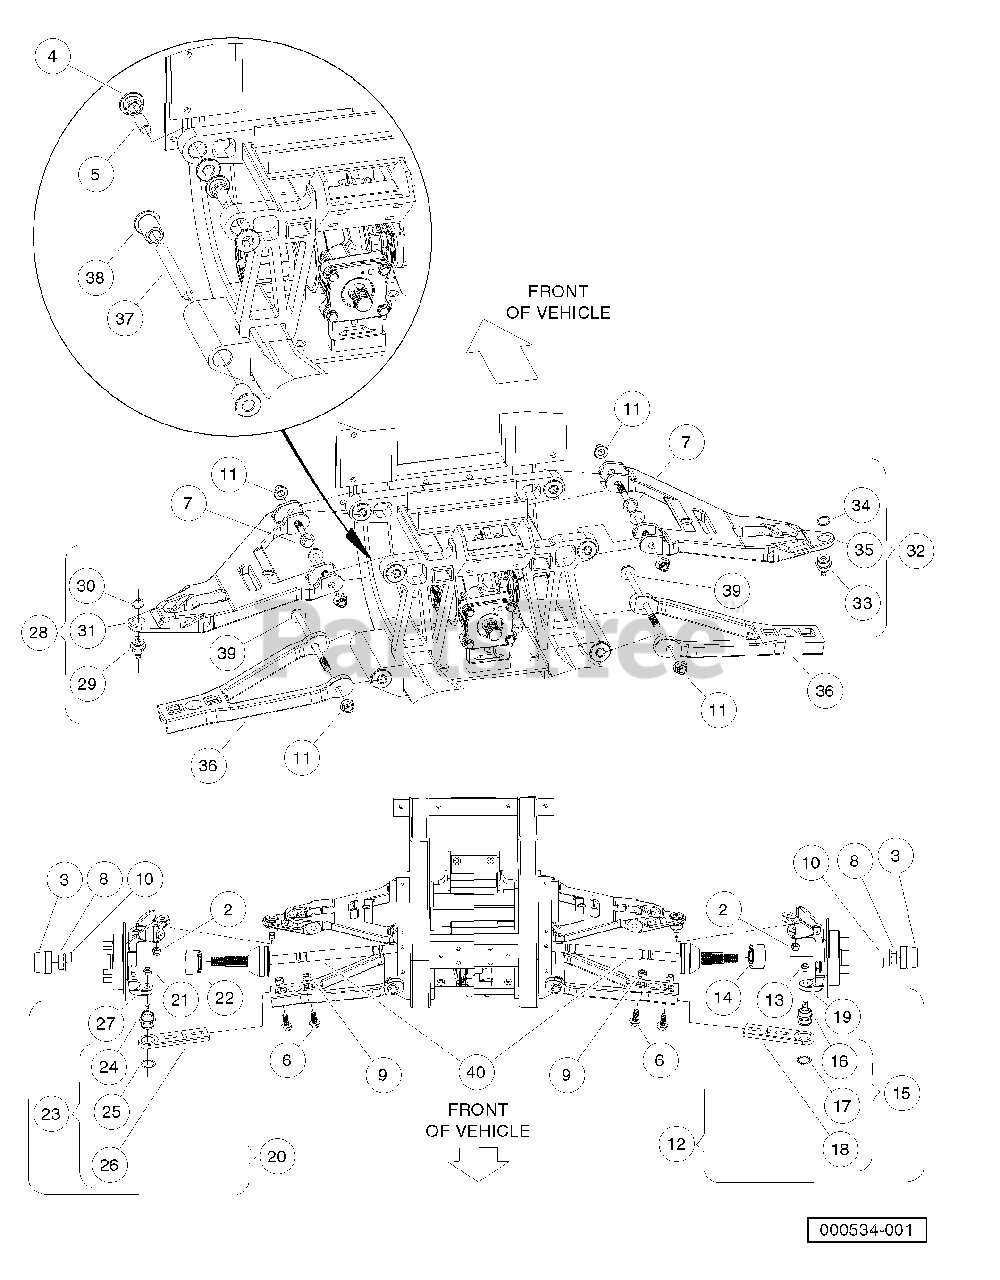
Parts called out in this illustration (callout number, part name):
1	Suspension, AWD, Wide
2	Locknut, M12-1.25 Nylon
3	Center Cap, Rubber
4	Bushing, A-Arm
5	Sleeve, Upper
6	Bolt, Flange Head, M12x 1.75x 30 with Loctite
7	Bolt, Flange Head, M12 X 1.75 X 70
8	Nut Flg, M22 X 1.5 Mech Def
9	Nut, Square, M12x 1.75
10	Washer Hard, M22
11	Nut Flg, M12x1.75, Nylon Gr 10
12	Upright, Left-Hand
13	Locknut, M12-1.25 Nylon
15	Asm, Adjuster, Slide
16	Joint, Ball
17	Ring, Retaining, Ext, 1-1/4"
18	Slide, Adjuster
19	Upright, Left, 40 X 74 X 40
20	Upright, Right-Hand
21	Locknut, M12-1.25 Nylon
23	Asm, Adjuster, Slide
24	Joint, Ball
25	Ring, Retaining, Ext, 1-1/4"
26	Slide, Adjuster
27	Upright, Right, 40 X 74 X 40
28	Asm, A-Arm, Upper, Left
29	Joint, Ball
30	Ring, Retaining, Ext, 1-1/4"
31	Arm, Upper, Wide, Machined, Lh
32	Asm, A-arm, Upper, Right
33	Joint, Ball
34	Ring, Retaining, Ext, 1-1/4"
35	Arm, Upper, Wide, Machined,rh
36	A-Arm, Lower
37	Sleeve, Lower Arm
38	Bushing, Lower Arm
39	Bolt Flg, M12 X 1.75 X 200 10
40	Half Shaft, Wide, Awd
